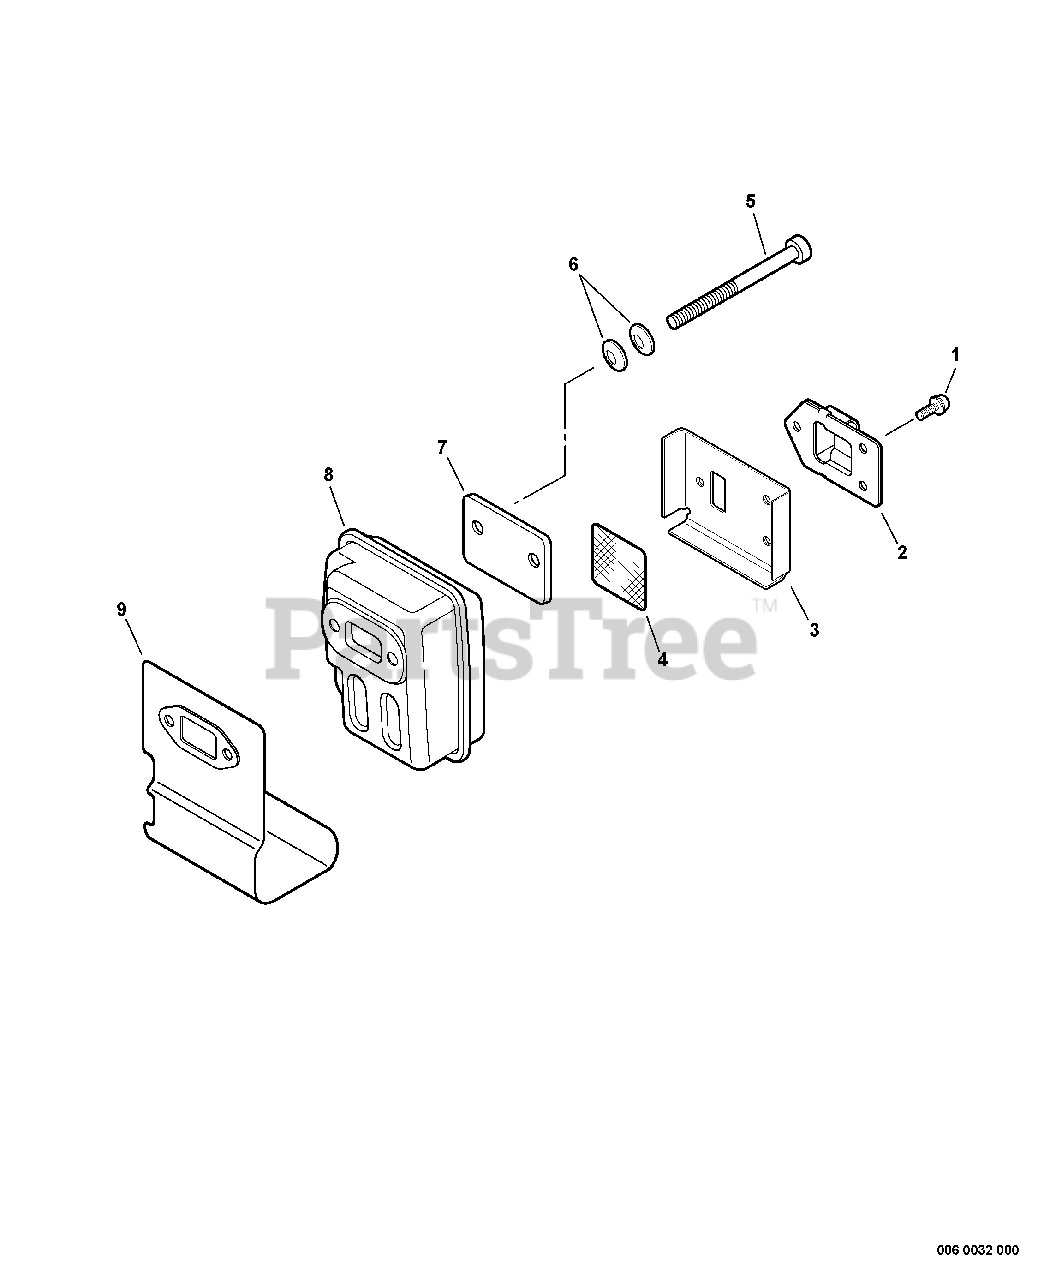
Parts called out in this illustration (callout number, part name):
1	SCREW 4×12
2	GUIDE, EXHAUST
3	GASKET, EXHAUST
4	SCREEN, SPARK ARRESTER
5	BOLT 5×55
6	CONICAL WASHER
7	PLATE, EYE
8	MUFFLER
9	SHIELD, EXHAUST
